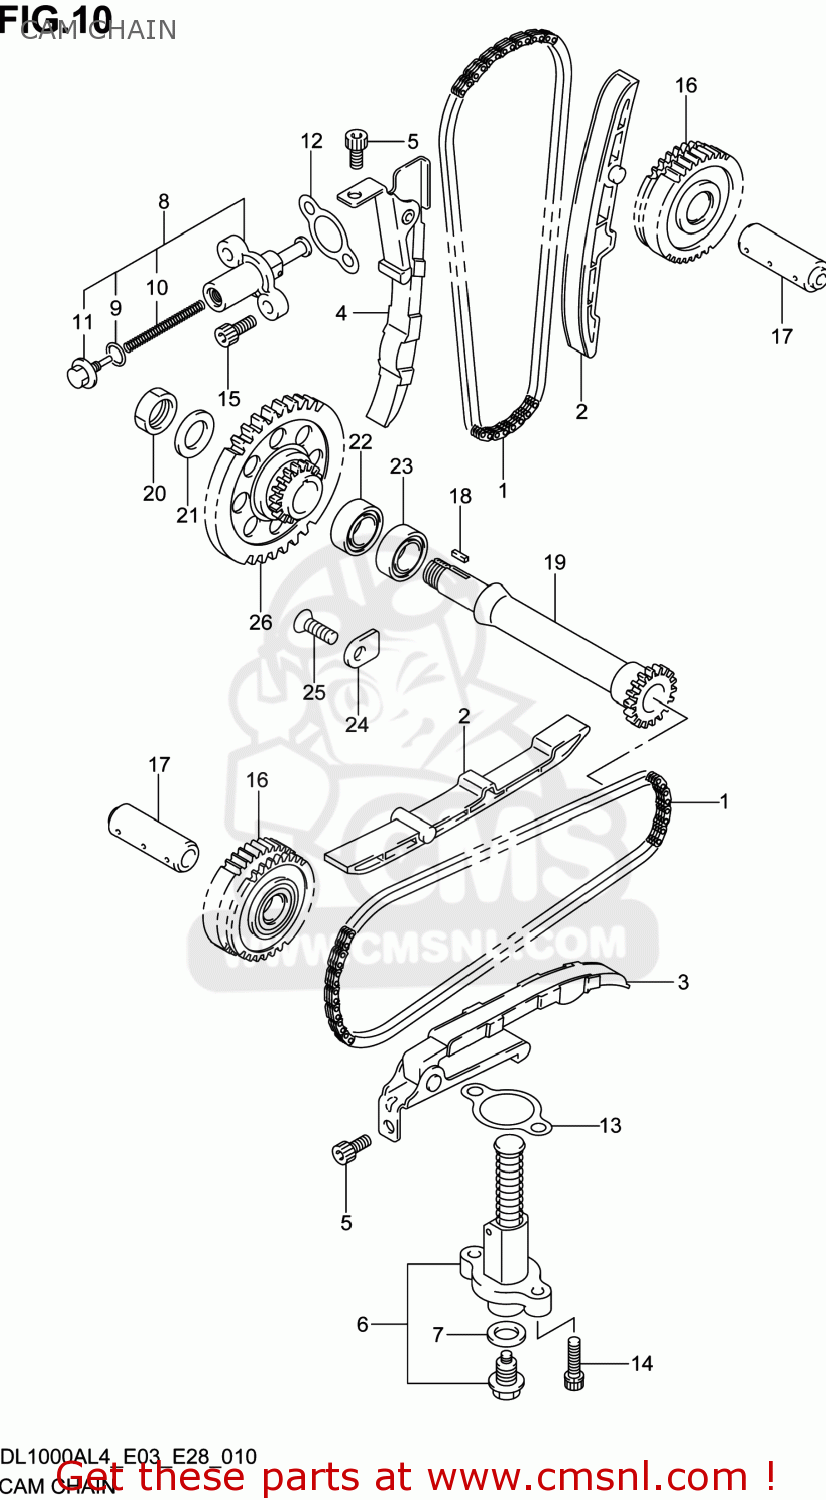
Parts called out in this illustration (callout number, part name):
1	CHAIN,CAMSHAFT DRIVE
2	GUIDE,CAM CHAIN
3	TENSIONER,CAM CHAIN FR
4	TENSIONER,CAM CHAIN RR
5	BOLT
6	ADJUSTER ASSY,TENSIONER FR
7	GASKET(12X21X2) (NAS)
8	ADJUSTER ASSY,TENSIONER
9	O RING
10	SPRING
11	PLUG,ADJUSTER
12	GASKET,TENSIONER ADJUSTER (NAS)
13	GASKET,TENSIONER ADJUSTER (NAS)
14	BOLT
15	BOLT
16	GEAR,CAM CHAIN IDLER NO.2
17	SHAFT,IDLER NO.2
18	KEY
19	SHAFT,IDLER
20	NUT
21	SHIM(16X26X1.5)
22	BEARING
23	BEARING(25X47X8)
24	RETAINER,COUNTER BEARING,R
25	SCREW(6X12)
26	SPROCKET,IDLER NO.1
